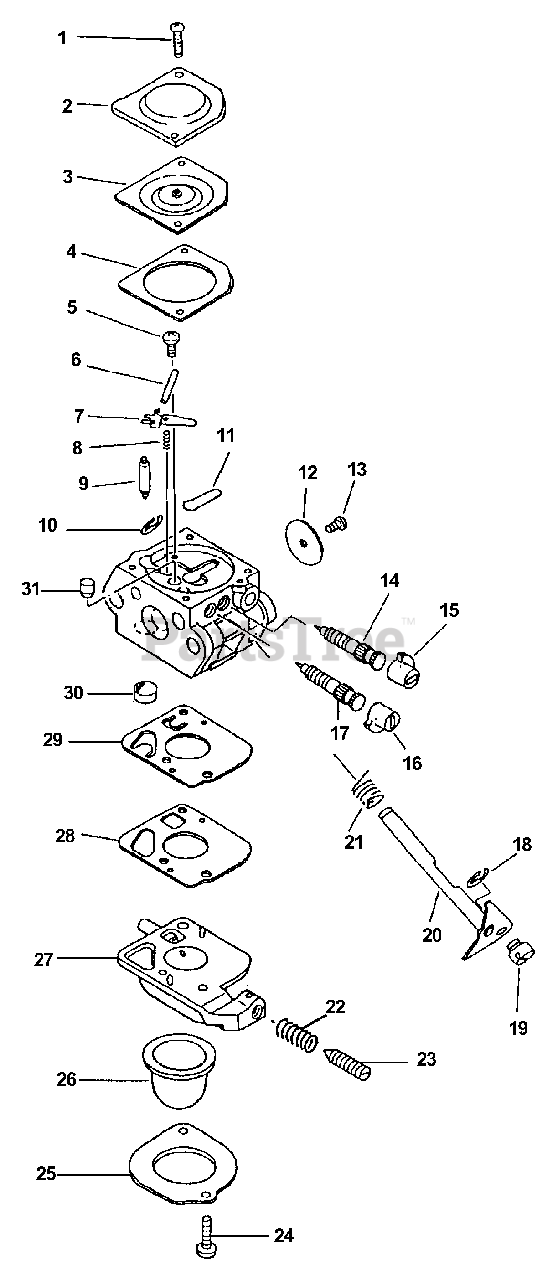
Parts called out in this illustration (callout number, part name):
2	COVER, METERING
3	DIAPHRAGM, METERING
4	GASKET, METERING
5	SCREW, METERING LEVER PIN
6	PIN, METERING LEVER
7	LEVER, METERING
8	SPRING, METERING LEVER
9	VALVE, NEEDLE
10	RING, RETAINING
11	PLUG, WELCH
12	VALVE, THROTTLE
14	NEEDLE - LOW SPEED
15	CAP, LIMITER
16	CAP, LIMITER
17	NEEDLE - HIGH SPEED
18	RING, RETAINING
20	SHAFT, THROTTLE
21	SPRING, RETURN
22	SPRING, IDLE ADJUST
23	SCREW, IDLE ADJUST
24	SCREW, RETAINER
25	RETAINER, PURGE BULB
26	BULB, PURGE
27	BASE, PURGE
28	GASKET, PUMP
29	DIAPHRAGM, PUMP
30	STRAINER
31	NOZZLE, CHECK VALVE
31	REPAIR KIT
31	DIAPHRAGM/GASKET KIT
